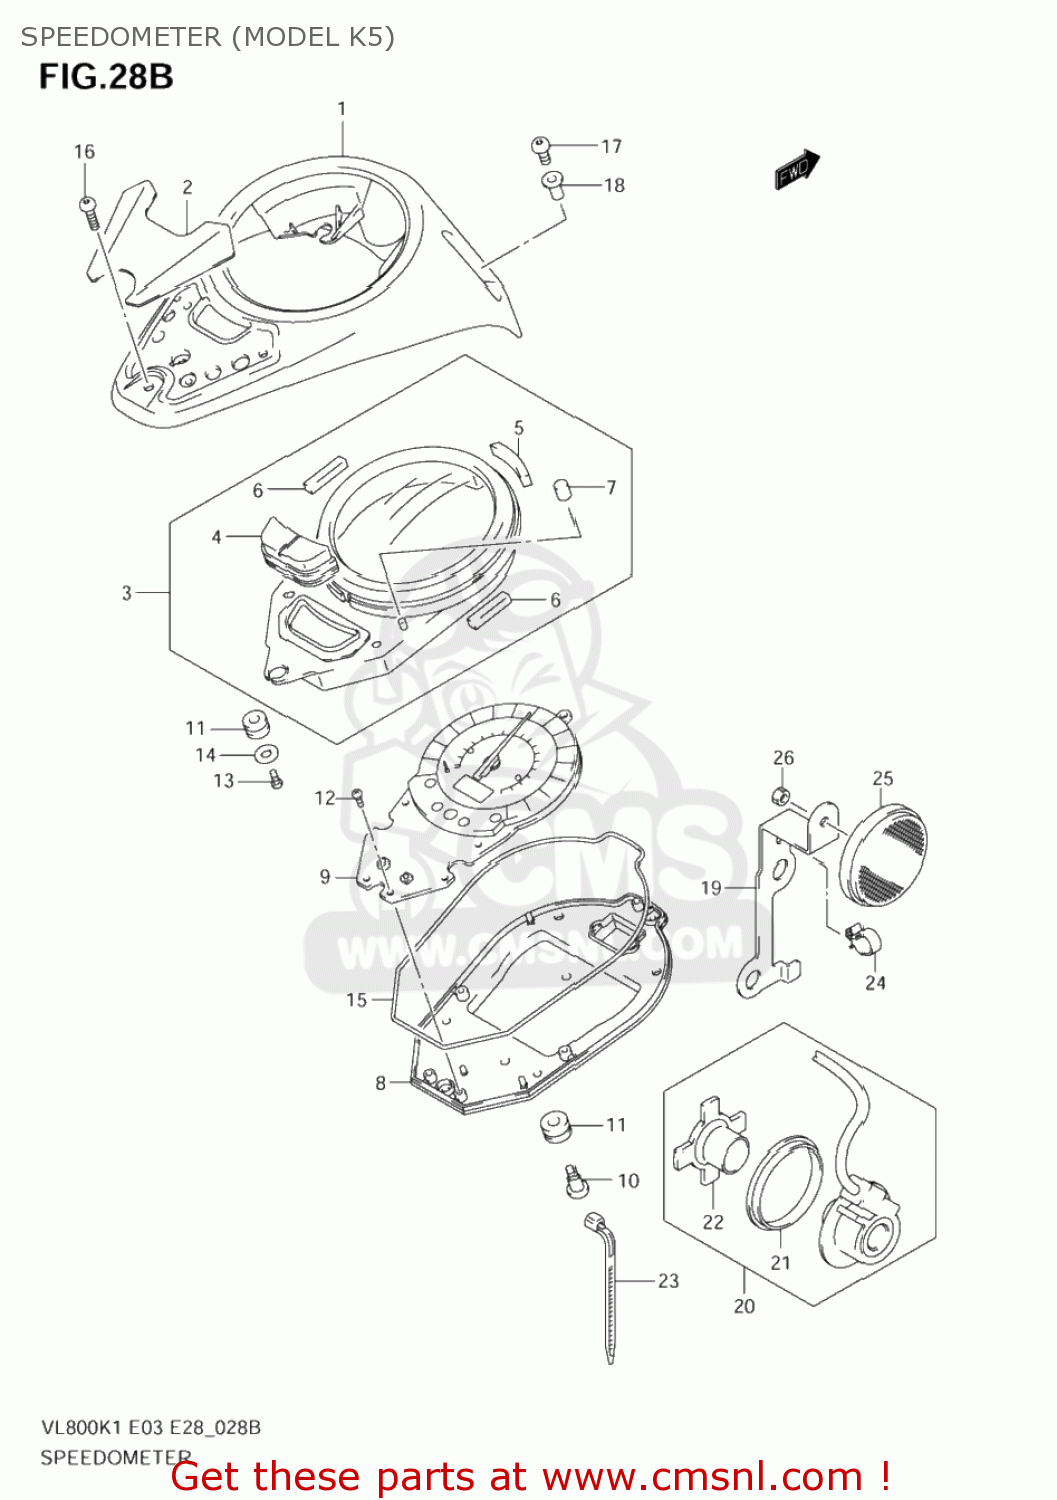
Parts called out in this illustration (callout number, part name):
1	CASE ASSY
2	PLATE,DECORATION
3	CASE,UPR
4	SWITCH,SELECT
5	CUSHION NO.1
6	CUSHION NO.2
7	CUSHION NO.4
8	CASE,LWR
9	SNELHEIDSMETER
10	BOLT
11	CUSHION,METER
12	SCREW(3X10)
13	SCREW(4X14)
14	WASHER
15	GASKET,METER CASE (NAS)
16	SCREW(5X14)
17	SCREW(5X18)
18	NUT
19	GUIDE,SPEED SENSOR LEAD
20	SENSOR,SPEED
21	SEAL,OIL(44X55X6)
22	MAGNETO
23	CLAMP(L:145)
24	CLAMP
25	REFLECTOR,REFLEX FR
26	NUT
